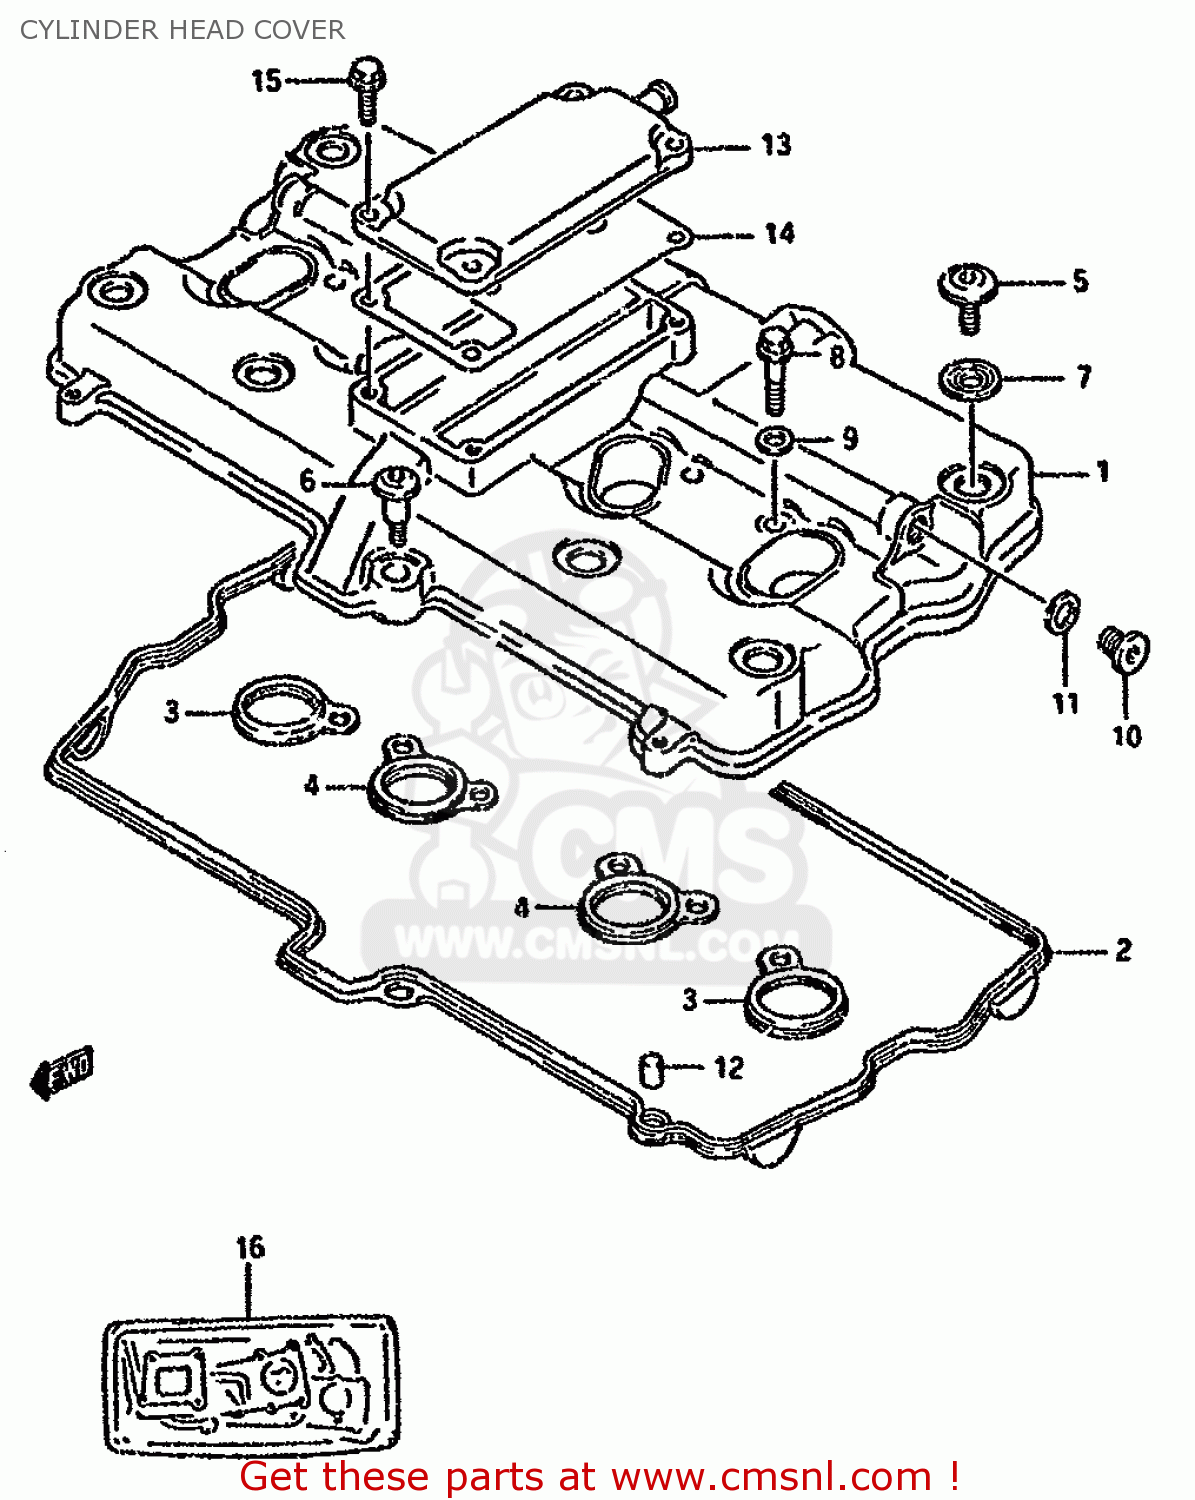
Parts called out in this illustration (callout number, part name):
1	COVER,CYLINDER HEAD
2	GASKET,CYLINDER HEAD COVER (NAS)
3	GASKET,HEAD COVER NO.2 (NAS)
4	GASKET,HEAD COVER NO.3 (NAS)
5	BOLT(7X17.5)
6	BOLT(7X31)
7	WASHER(10.6X25.5X2.3)
8	BOLT,UNION 8X35
9	GASKET 8.2X14X1 (NAS)
10	PLUG(L:12)
11	GASKET(12.1X16.2X3.7) (NAS)
12	PIN
13	COVER,BREATHER
14	GASKET,BREATHER COVER (NAS)
15	BOLT 6X20
16	GASKET SET
